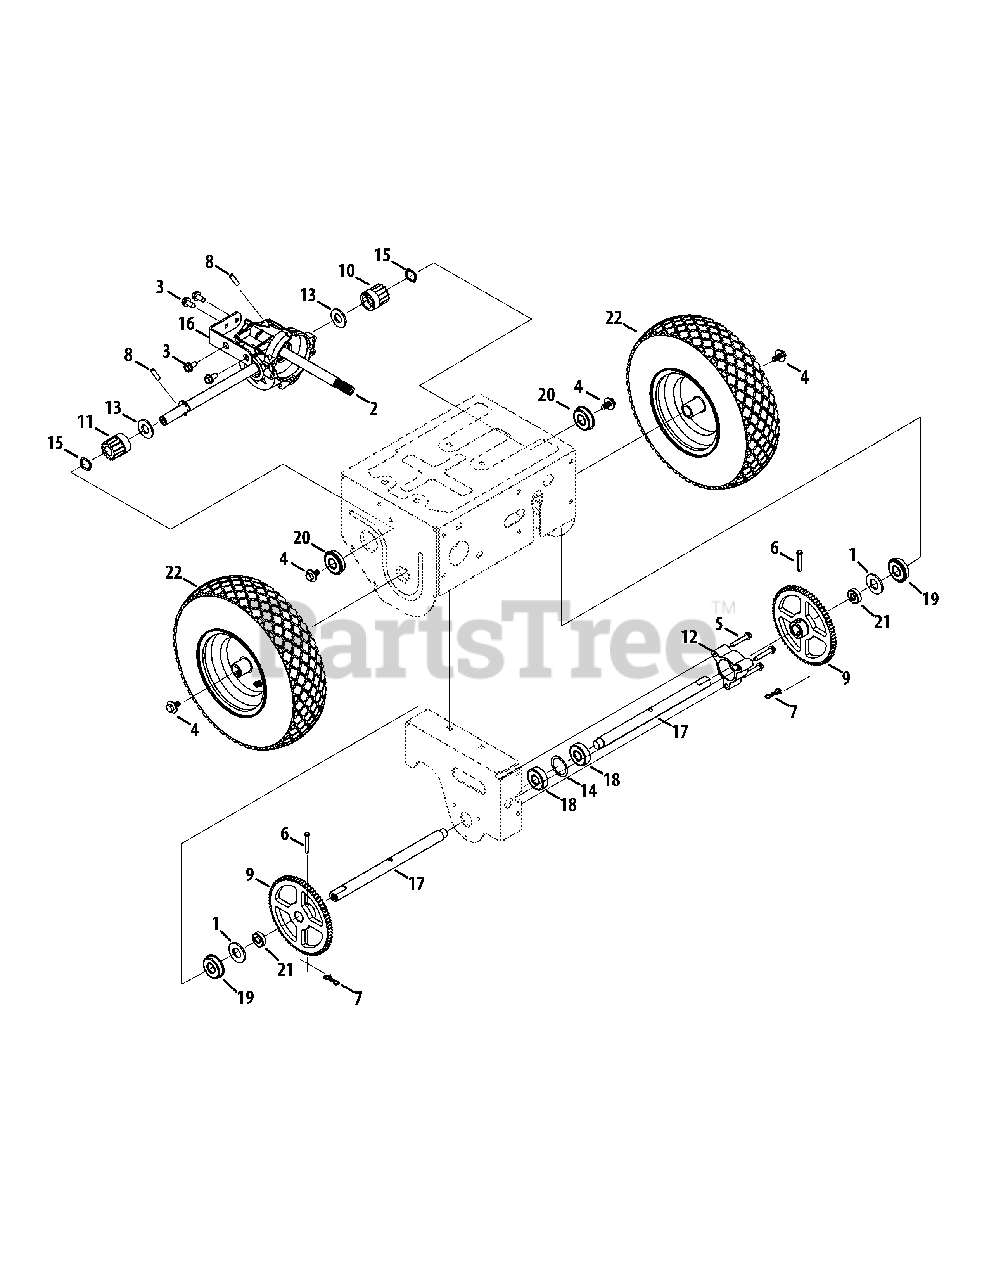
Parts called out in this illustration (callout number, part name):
1	Washer, .764 x 1.312 x .091
2	Transmission Assembly
3	Hex Washer Screw, 5/16-18 x .750
4	Hex Cap Screw, 5/16-24 x .750
5	Self-tapping Screw, 1/4-20 x 1.625
6	Clevis Pin, 1/4 x 1.3725
7	Bow-Tie Cotter Pin, 72
8	Square Key, 1/4 x .845
9	Gear, 70 Tooth
10	Gear, Spur, 14T, LH
11	Gear, Spur, 14T, RH
12	Cup, Bearing
13	Flat Washer, .677 x 1.375 x .120
14	Washer, 1.25 x 1.57 x .01
15	Wave Washer, .681 x .869 x .014
16	Transmission Bracket
17	Axle, .75 OD x 10.95 Lg
18	Ball Bearing
19	Ball Bearing, 75 x 40 x 12
20	Ball Bearing, 17 x 40 x 12
21	Spacer, .76 ID x 1.16 OD x .25
22	Wheel, 13 x 4
